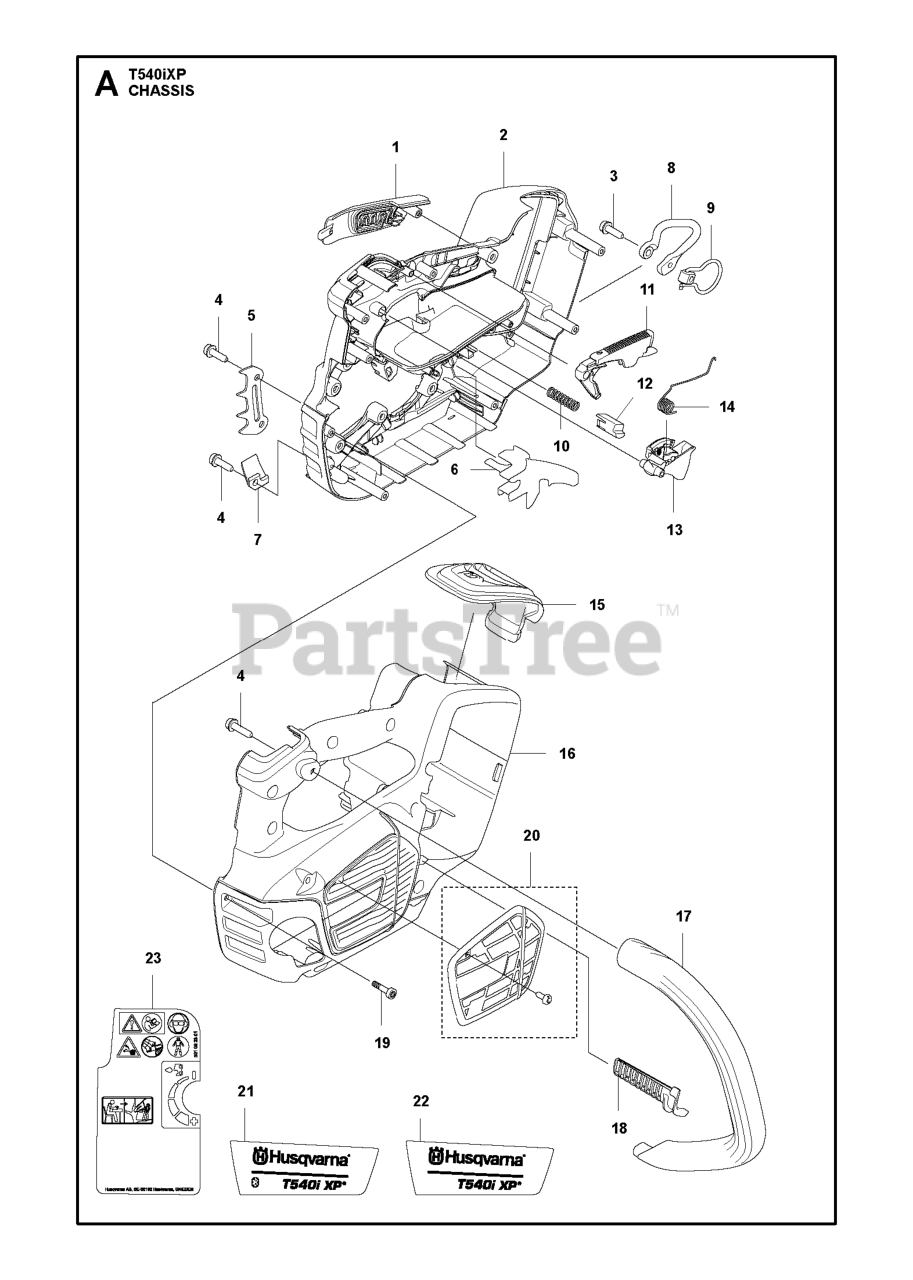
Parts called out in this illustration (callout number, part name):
2	Chassis
3	SCREW ITXSCFM
5	INDRE BARKSTØD
6	Air Conductors
7	CHAIN CATCHER
10	SPRING PUSH OUT
12	PUSH BUTTON
15	Covers
16	CHASSIS FLYWHEEL SIDE
18	Air Filters
19	SCREW ITXSCT PW4.2X18 10.9 ZN
23	DECAL - WARNING
